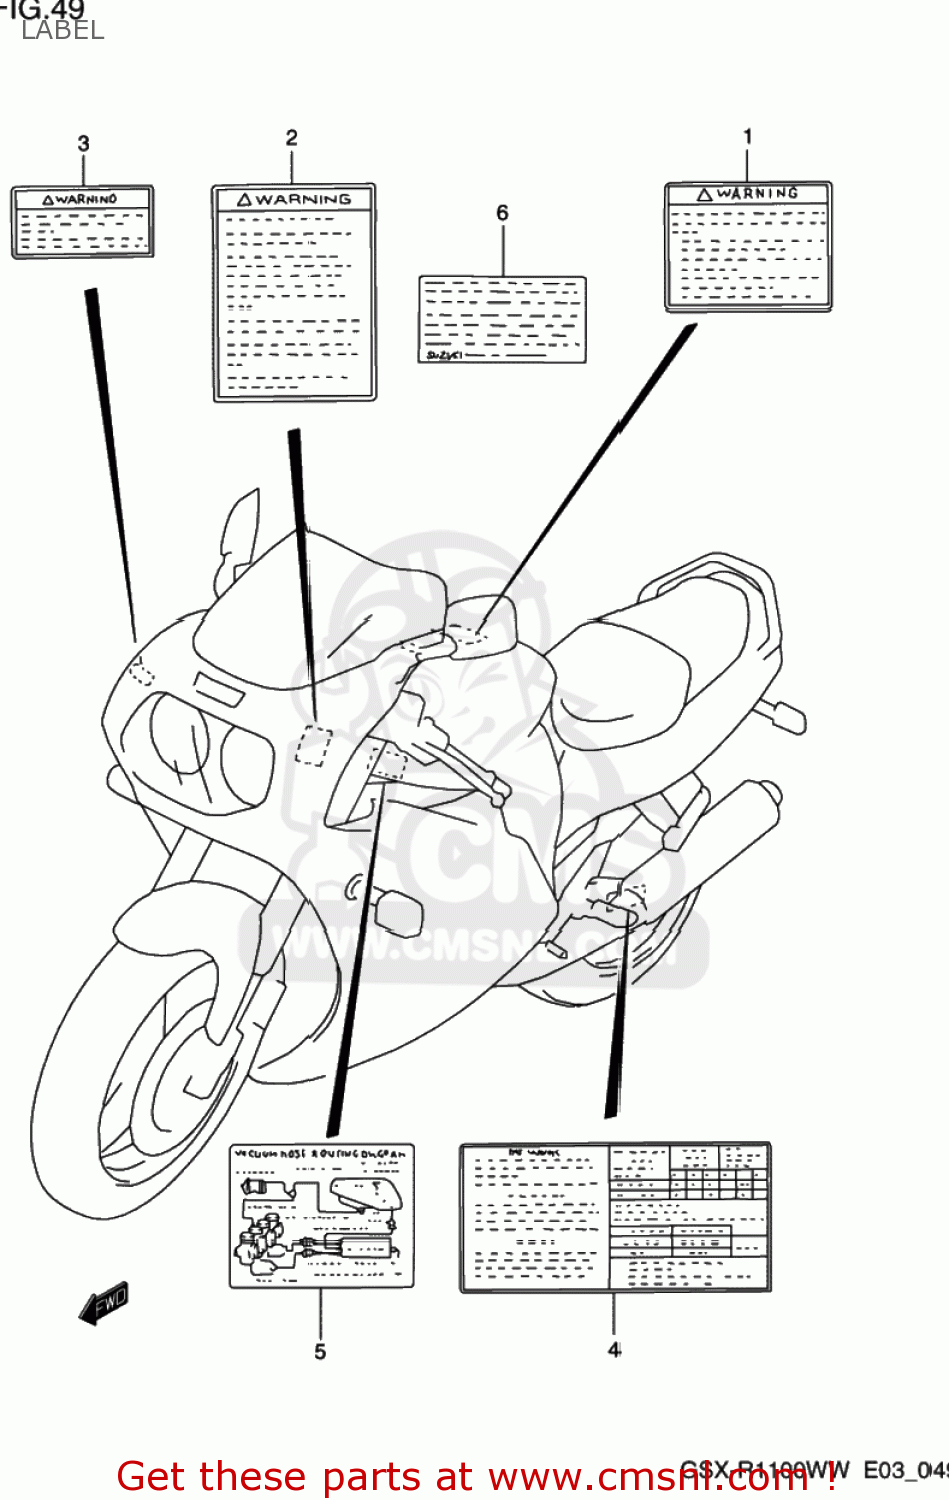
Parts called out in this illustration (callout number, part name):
1	LABEL
2	LABEL (WARNING SCREEN)
3	LABEL,WARNING STEERING
4	LABEL (TIRE INFORMATION)
5	LABEL (VACUUM HOSE ROUTING)
6	LABEL (MANUAL NOTICE)
7	MANUAL, OWNER'S
